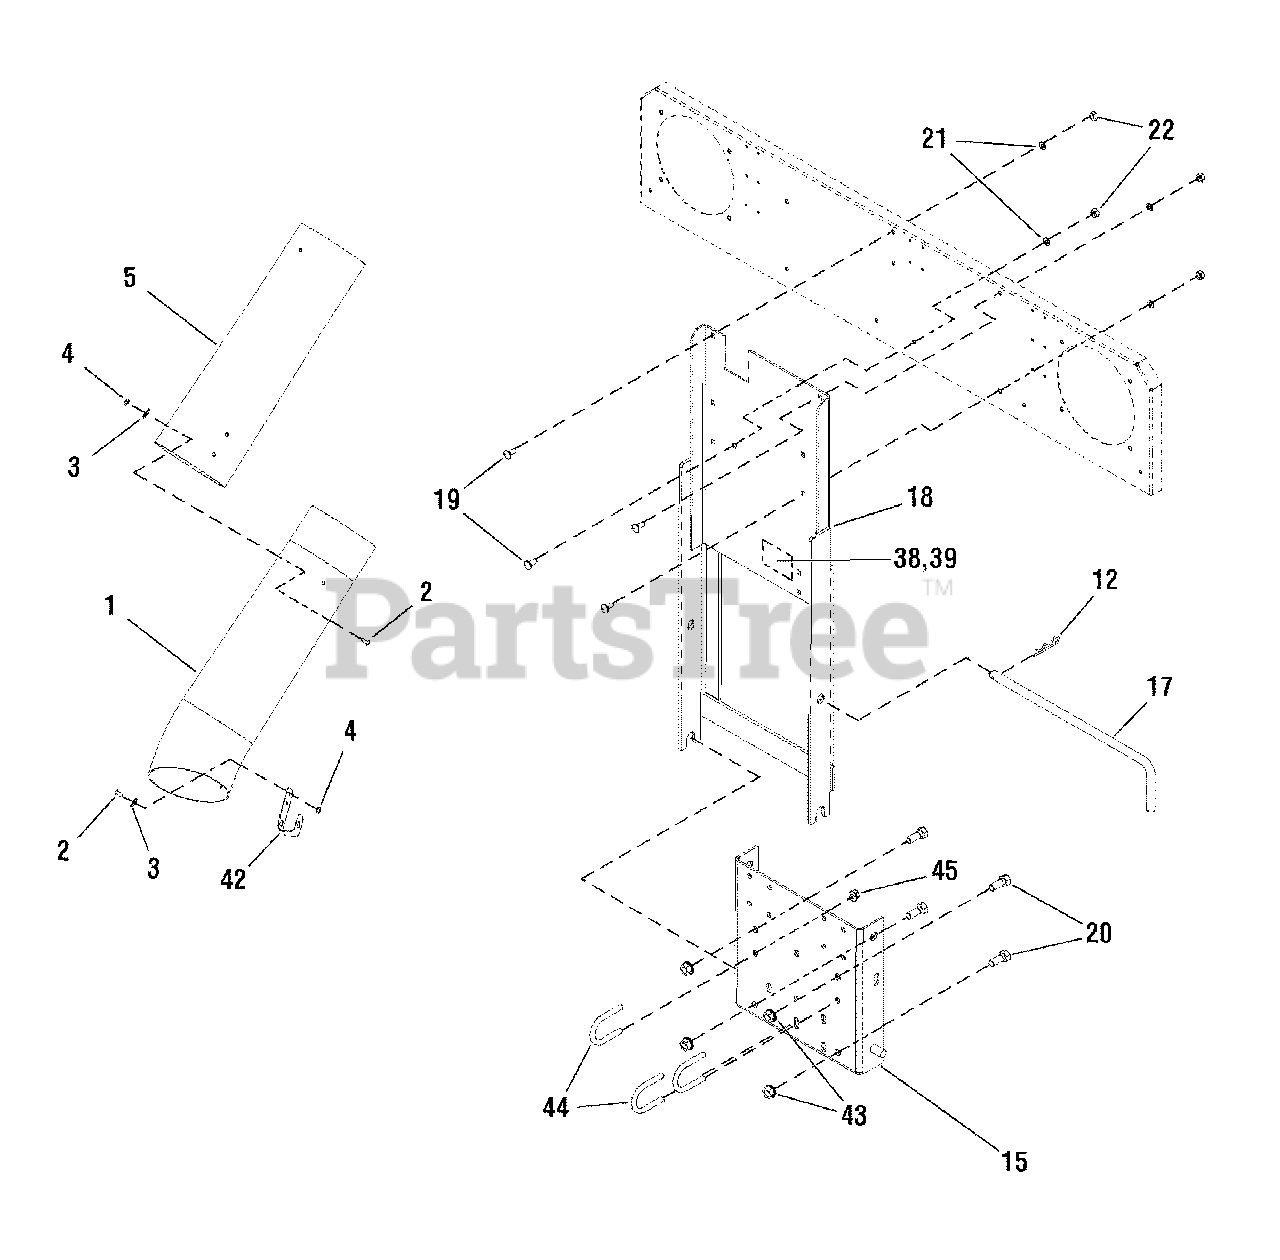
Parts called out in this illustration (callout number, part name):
2	SCREW, Truss Head, #10 - 24 x 3/4
4	NUT, Hex Nylock, #10 - 24
5	TUBE, Mid-Section
12	CLIP, Hairpin
15	HITCH PLATE ASSEMBLY
18	SUPPORT ASSEMBLY
19	BOLT, Carriage, 5/16 - 18 x 1
20	CAPSCREW, Hex Head, 1/2 - 13 x 1-1/4
21	LOCKWASHER, 5/16
22	NUT, Hex, 5/16 - 18
38	DECAL I.D.
39	OVERLAY, Mylar
42	CLIP, Spring
43	NUT, Hex Whiz Lock Flange, 1/2 - 13
44	U-BOLT, 3/8 x 1-1/4
45	NUT, Hex Flange, 3/8 - 16, ESNA
46	OPERATORS MANUAL
